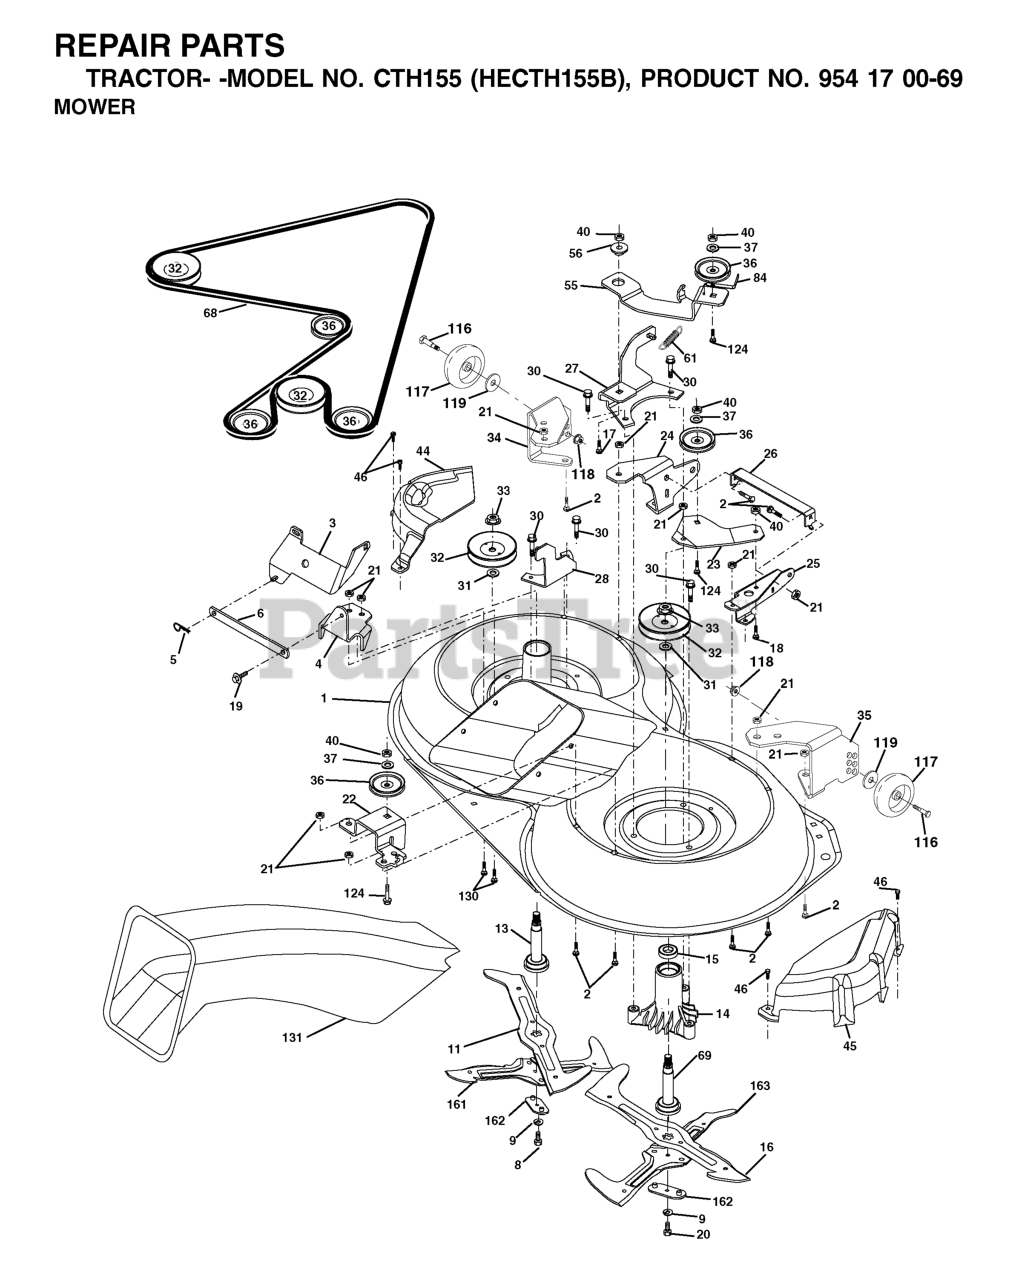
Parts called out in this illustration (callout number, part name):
1	MOWER HOUSING, DECK
2	RP BOLT 5/16-18 X3/4 ZN/YEL GR
5	RETAINER-SPRNG RB
6	BAR.SWAY.92.CRD
8	BOLT.3/8-24X1.25 GR8
9	LOCKWASHER
11	BLADE-LH 5PT STAR(CTH130)
13	SHAFT ASM VENT
14	HOUSING.MANDREL.VENTED (MACHD)
16	BLADE RH 6PT STAR(CTH130)
17	BOLT.3/8-14X1.25
18	BOLT D
19	BOLT SHD 5/16-18
20	BOLT.3/8-24X1.25GR8. LHTHRD
21	LOCKNUT
26	BRACE.SUPT.SUSP.FRT.CRD
30	SCREW, WASHER HEAD
31	WASHER
32	PULLEY, MANDREL
33	NUT, FLG TOPLOCK 9/16"
36	PULLEY.IDLER.4.25
37	WASHER
45	COVER.MANDREL.RH.CRD
46	SCREW.1/4-20X5/8
56	SPACER.RETAINER.MOWER
61	SPRING.TENSION.BELT
68	HEX-BELT
69	SHAFT.ASM.W/LWR.BRG.RH.THREAD
84	KEEPER, BELT IDLER
116	BOLT, SHOULDER
117	WHEEL GAGE DONUT
118	LOCKNUT
119	WASHER.5/16.FLAT.STE.STD.
124	BOLT.3/8-16X1.50
130	BOLT.CARR.SQNK.5/16-18UNC.X3/4
131	CHUTE BAGGER
162	ADAPTER.BLADE.PNT.CSS.36/38/42
